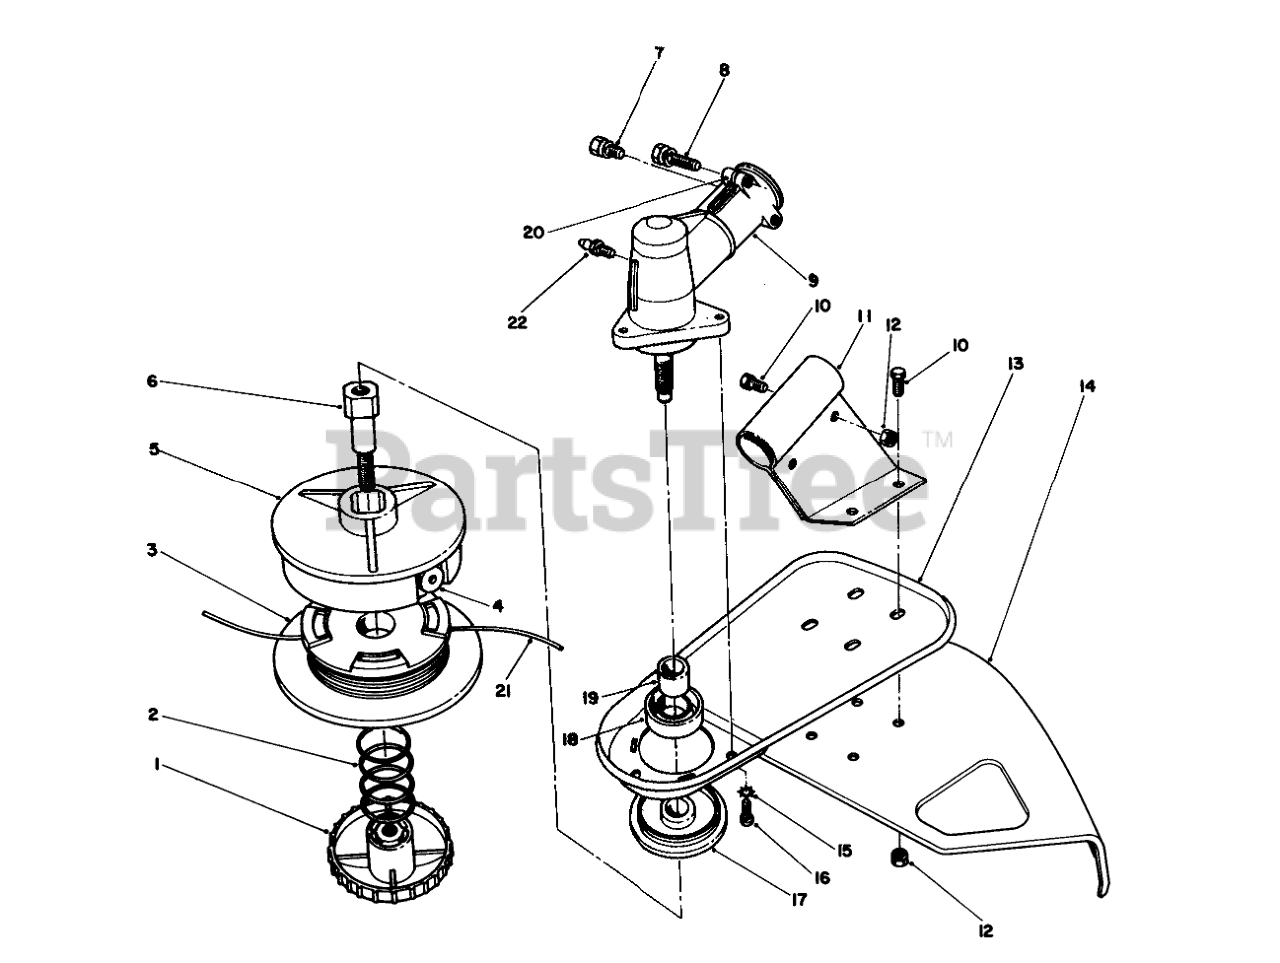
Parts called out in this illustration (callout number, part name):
1	Knob-L.H.
2	Spring
3	Spool-Inner
4	Eyelet
5	Housing-Spool
6	SHAFT ADAPTER
7	HHMS SCREW
8	HHMS SCREW
9	Gear Box Assembly (Incl. Ref. #7, 8, 17-20)
10	SCREW-SHH
11	SHIELD BRKT
12	NUT-LOCK, NI
13	SHIELD SUPPORT R
14	GRASS SHIELD R
15	WASHER-LOCK, EXT
16	SCREW
17	DUST CAP F/W
18	OIL SEAL
19	SPLINED SLEEVE
20	WASHER
21	REPL LINE PKG
